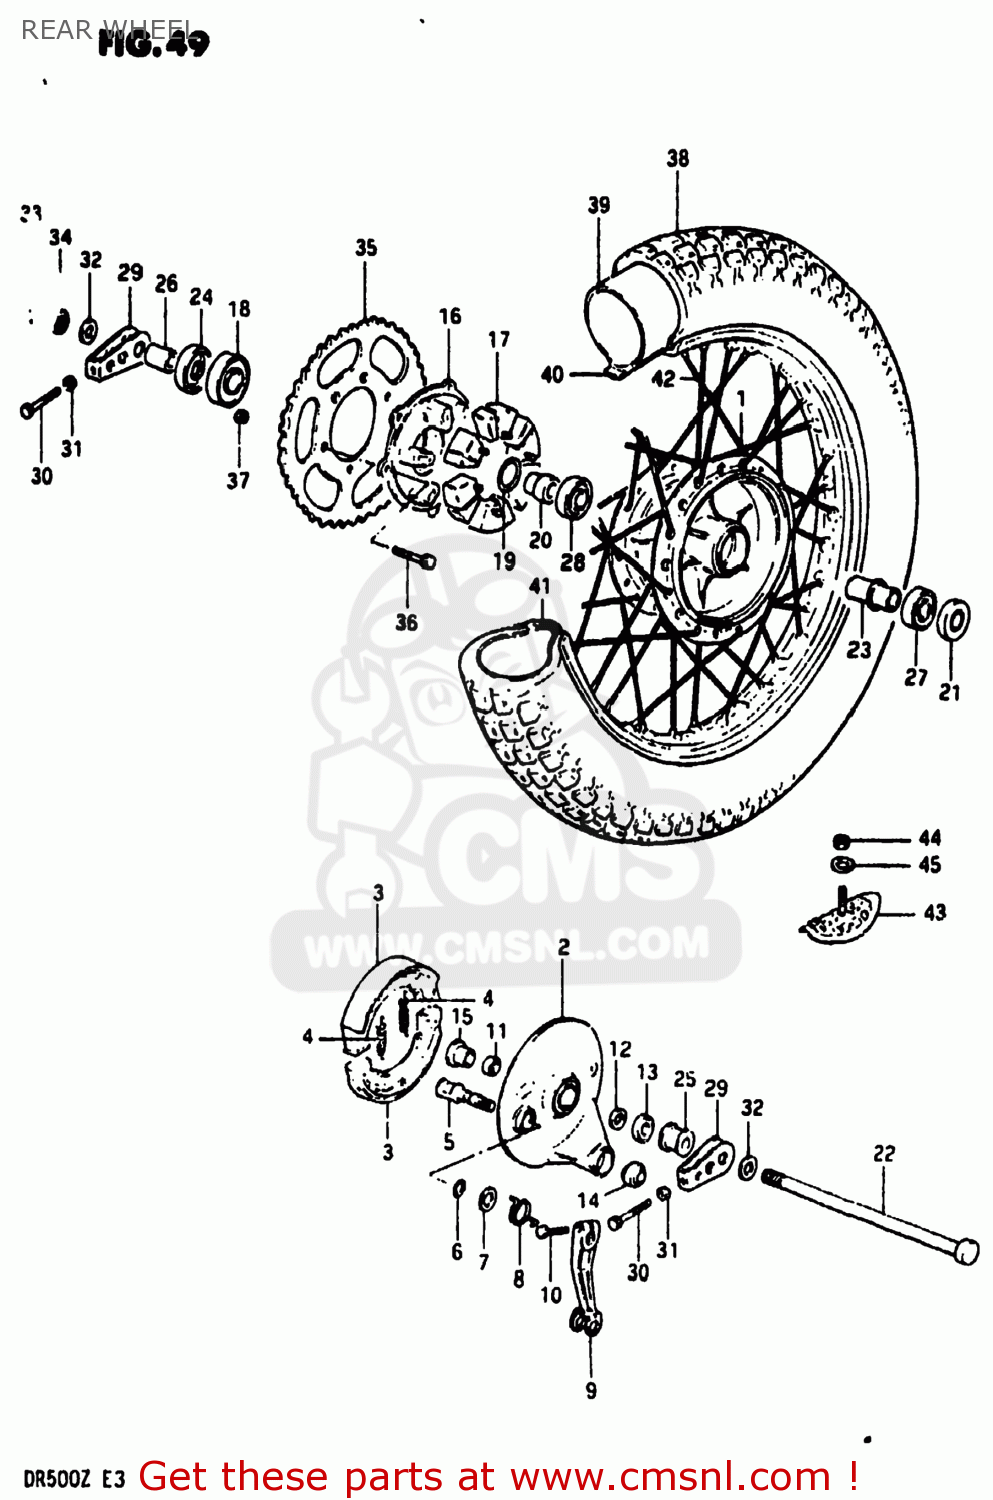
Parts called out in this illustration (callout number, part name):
1	DRUM,REAR HUB
2	PANEL,REAR HUB
3	SHOE,BRAKE (MCA)
4	SPRING
5	CAM,FRONT BRAKE
6	O-RING,BOSS
7	WASHER (15X24X1.6)
8	SPRING
9	LEVER,REAR BRAKE CAM
10	BOLT
11	BEARING(24X31X28)
12	WASHER
13	CVR,RR BRAKE AHR PNL DUST SEAL
14	SPHERICAL BRNG,TORQUE LINK
15	SPACER,REAR HUB PANEL
16	DRUM,REAR SPROCKET MOUNT
17	ABSORBER,RR HUB SHOCK
18	BEARING
19	O-RING
20	SPACER,REAR SPROCKET DRUM
21	OIL SEAL
22	AXLE,REAR
23	SPACER,REAR HUB BEARING
24	SEAL,OIL(30.5X52X8)
25	SPACER,REAR AXLE,RIGHT
26	SPACER (17X30.5X12.9)
27	BEARING
28	BEARING
29	ADJUSTER,CHAIN
30	BOLT
31	NUT
32	WASHER (17X30X3.2)
33	PIN,COTTER
34	NUT
35	SPROCKET,REAR (NT:47)(AL)
36	BOLT
37	NUT
38	TIRE
39	TUBE,INNER
40	PROTECTOR,WHEEL,INNER
41	RIM,REAR WHEEL 2.15X18)(
42	SPOKE SET,REAR
43	STOPPER,BEAD
44	NUT
45	WASHER
